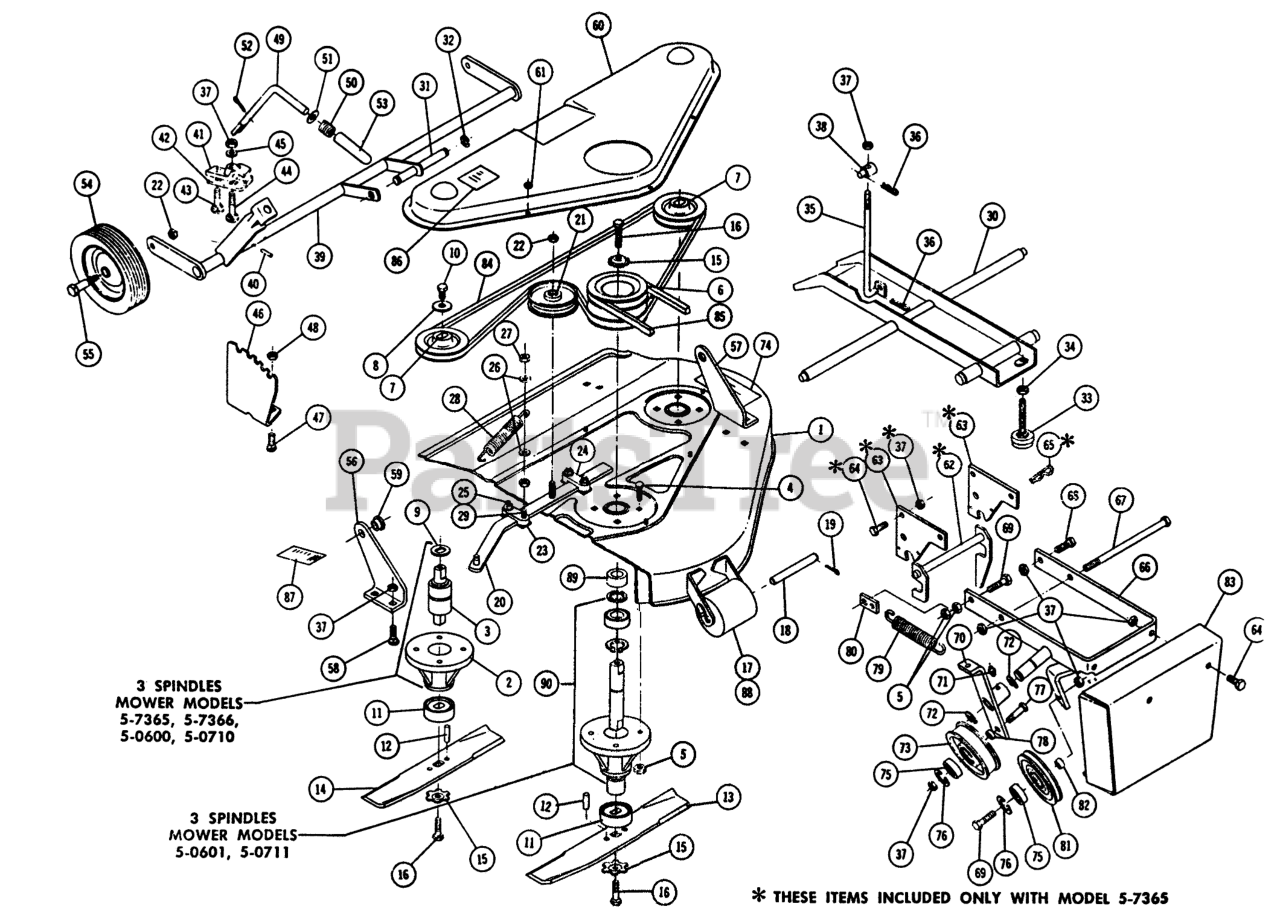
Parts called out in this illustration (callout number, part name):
1	Deck-Mower
1	Deck-Mower (5-0710 & 5-0711)
2	Housing
3	Bearing-Spindle
4	Bolt Carriage 3/8-16 x 1
6	Pulley
6	Pulley-Middle Drive
7	Pulley
7	Pulley-End
8	WASHER
9	WASHER
10	Bolt 3/8-16 x 3/4 Hex
11	Cup-Spindle
12	SPIROL ROLL PIN
13	Blade 14"
13	Blade 14" (5-0710 & 5-0711)
14	Blade 12"
14	Blade 12" (5-0710 & 5-0711)
15	WASHER
16	Bolt 3/8-16 x 7/8
17	Roller
18	Shaft
19	Cotter Pin
20	Bar Idler Support
21	Idler Pulley
22	3/8-16 Jam Nut
23	SLIDE
24	Side Block
25	Bolt-5/16-18 x 1/4
26	Washer
27	Nut-Nylok
28	SPRING R
29	Bolt-5/16-18 x 1 1/2
30	Lift Frame
31	Pin
32	E Ring
33	Leveler
35	ROD LIFT
36	Hairpin
37	3/8-16 E.S.
38	TRUNNION-LIFT
39	Screw-Conn. Rod
40	Roll Pin
41	Support
42	Clip
43	Bolt Carriage 3/8-16 x 1
44	Bolt Carriage 3/8-16 x 2
45	Washer
46	Quadrant
47	Bolt Hex 5/16-18 x 3/4
48	Nut 5/16-18
49	FORK
50	Spring
51	Washer
52	Hairpin
53	GRIP
54	Wheel
55	BOLT-SHOULDER
56	Bracket-Hanger L.H.
57	Bracket-Hanger R.H.
58	Bolt 3/8-16 x 1
59	BUSHING
60	Cover
61	HEX NUT 10-32 E.S.
62	ASSY LATCH & SHAF R
63	PLATE-MTG BRKT LH R (NS)
64	Bolt 3/8-16 x 1
65	Hairpin
66	Frame-Idler Support
67	Bolt-Hex 3/8-16 x 8
68	Bolt 3/8-16 x 1
69	Bolt Hex 3/8-16
70	ASSY IDLER ARM SU R
71	Zerk
72	E-RING
73	PULLEY IDLER
74	Decal
75	BEARING
76	INTERNAL SNAPRING
77	Bolt 3/8-16 x 1 5/8
78	SPACER
79	SPRING-EXTENSION
80	PLATE SPRING ANCHOR
81	PULLEY IDLER
82	SPACER
83	Belt Cover
84	V-BELT
85	V-BELT
86	Decal-Belt Installation
87	Decal-Height Adj.
88	BUSHING
89	SPACER-PULLEY
90	Assy.-Sealed Spindle Bearing
